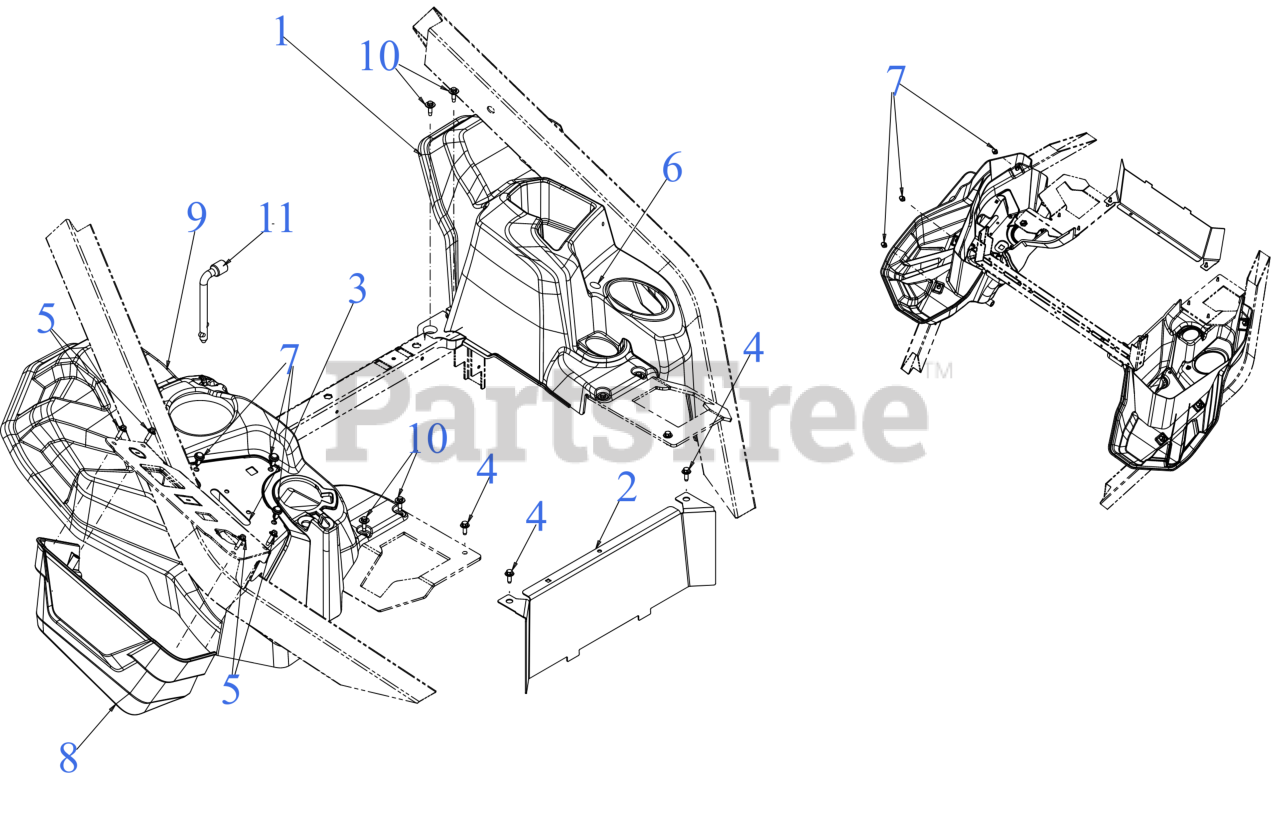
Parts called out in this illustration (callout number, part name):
1	CONSOLE (LH)
2	SEAT BOX FRONT PLATE
3	THROTTLE COVER PLATE
4	SCREW M6-1 x .625
5	SCREW 1/4-10 x .750
6	RATCHET CLIP
7	PLASTIC RIVET
8	CONTROL PANEL CONSOLE
9	CONSOLE (RH)
10	SHOULDER SCREW M6-1 .368 X.115
11	MULTI TOOL-1/2" SOCKET
